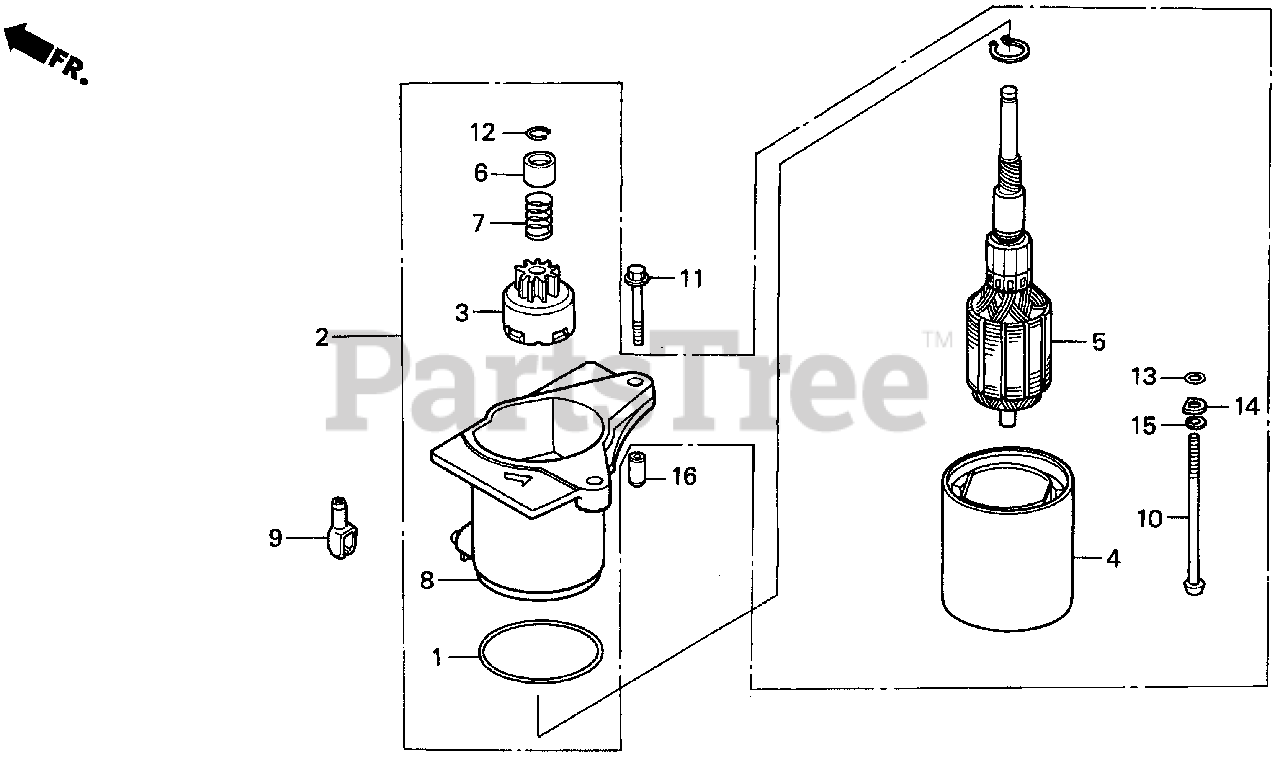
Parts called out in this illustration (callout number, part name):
1	O-RING
2	MOTOR UNIT, STARTER
3	GEAR ASSY., PINION
4	YOKE ASSY.
5	ROTOR ASSY.
6	PIECE, STOPPER
7	SPRING, RETURN
8	BRACKET, FR.
9	COVER, TERMINAL
10	BOLT, SETTING
11	BOLT, FLANGE (6X32)
12	CIRCLIP (OUTER) (8.3MM)
13	O-RING
14	WASHER, SPECIAL
15	WASHER, SPRING
16	PIN A, DOWEL (8X14)
